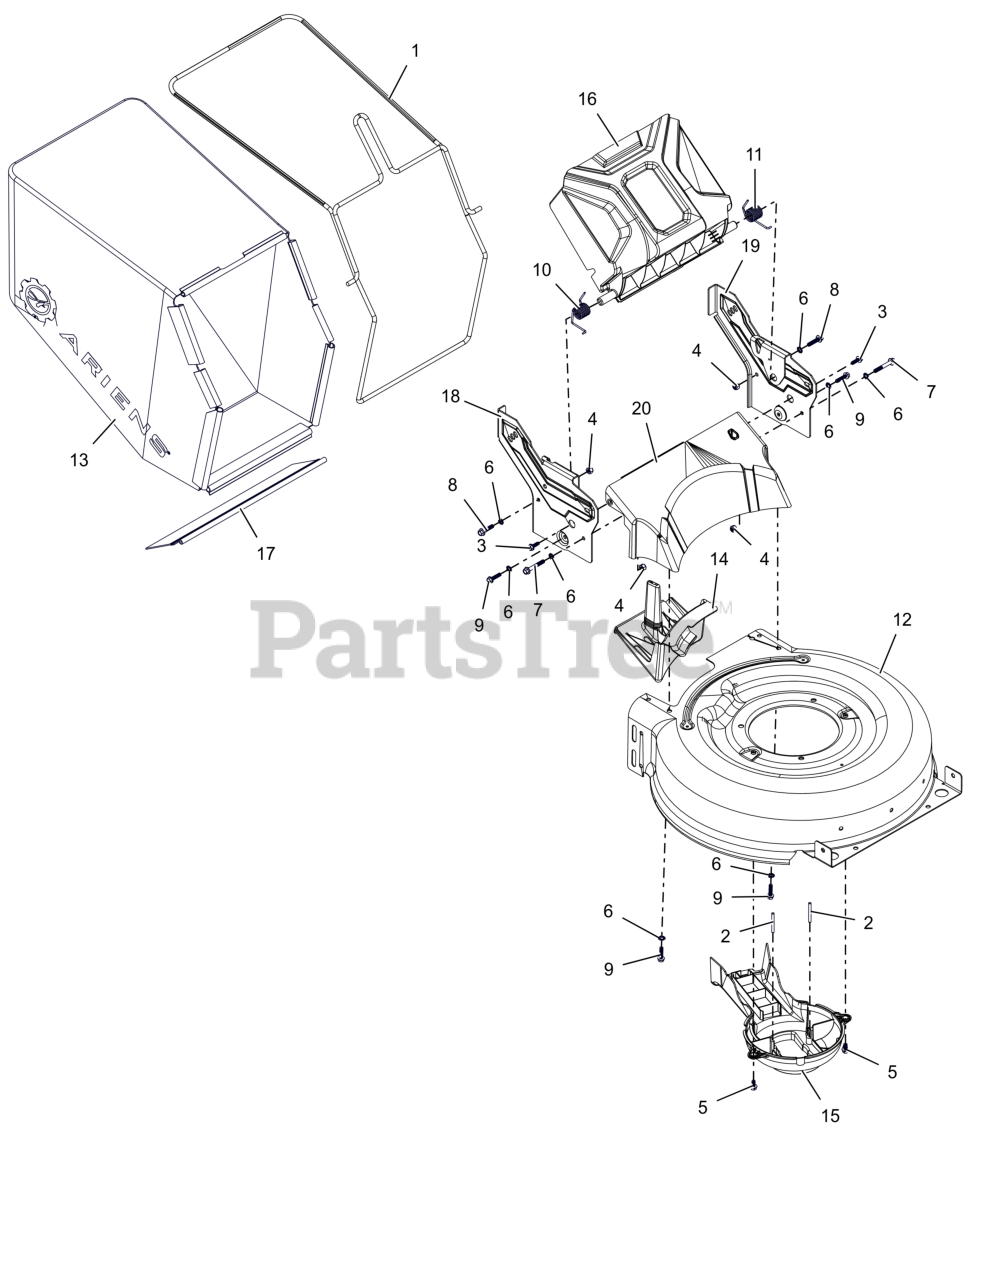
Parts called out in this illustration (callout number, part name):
1	WLDMT, BAG FRAME (ORANGE)
2	PIN, .188 X 1.750
3	SCR, HI-LO HWH 1/4-15 X .750
4	NUT, NYLOC 1/4-20
5	SCR, 1/4-20X.500, THREAD FORMING
6	WSHR-LK-EXT, .256X.510X.028
7	BLT, HEX 1/4-20 X 1.75 GR5
8	BLT, HEX 1/4-20 X 1.125
9	SCR, HI-LO HWH 1/4-15 X 1.00
10	SPRG, TORSION - DOOR LH
11	SPRG, TORSION - DOOR RH
12	DECK, RWD -21 (ORANGE)
13	BAG, ARIENS
14	PLUG, MULCH
15	COVER, RWD PULLEY
16	DOOR, REAR
17	GUARD, REAR DECK
18	BRKT, RH SIDE - RWD (BLACK)
19	BRKT, LH SIDE - RWD (BLACK)
20	COVER, BACK - RWD
